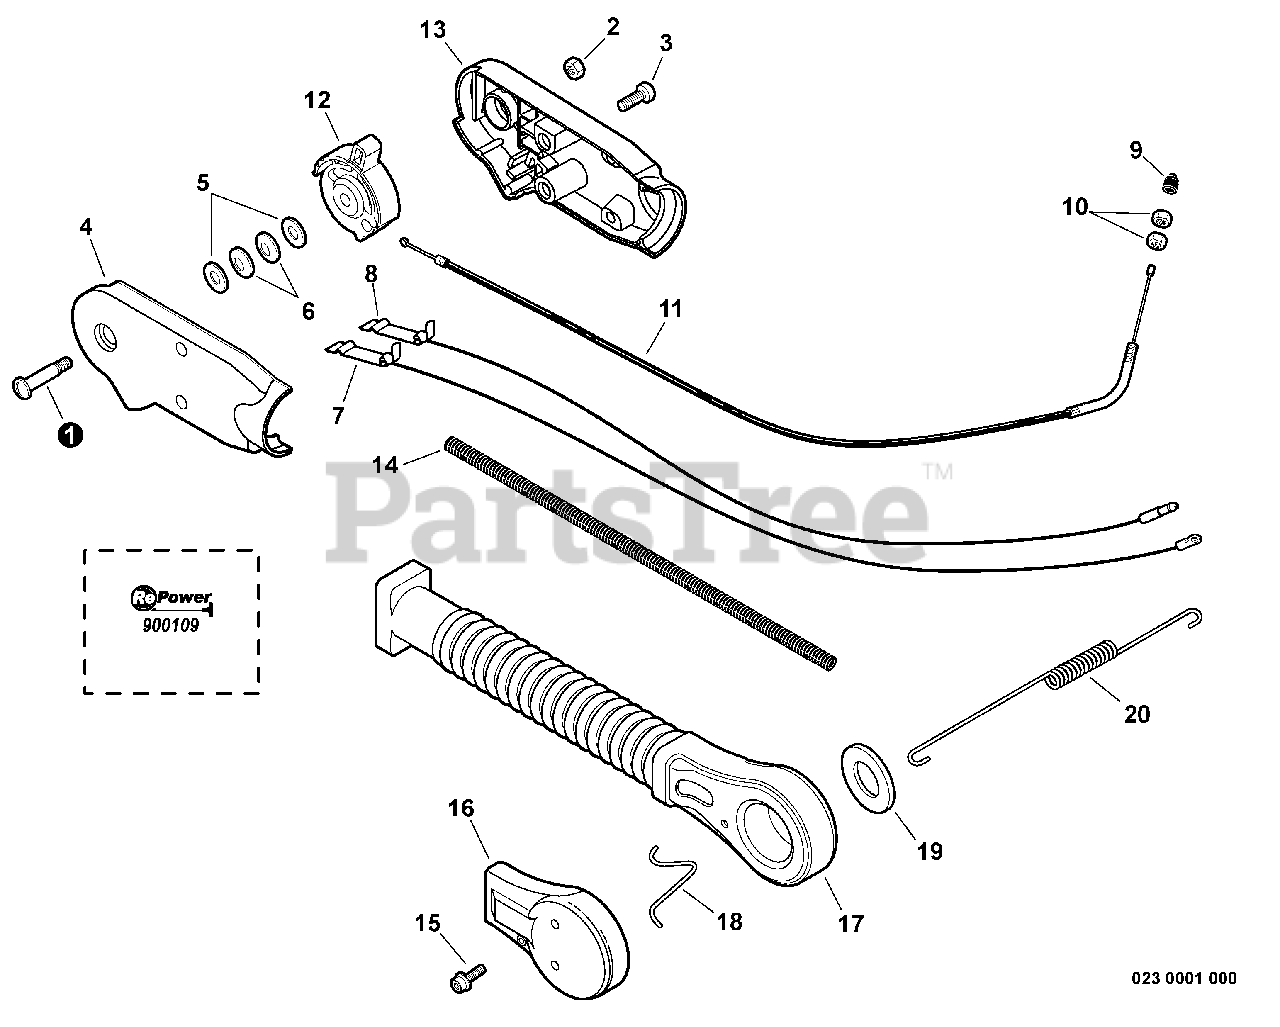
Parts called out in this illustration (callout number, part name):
1	SCREW - 4
2	LOCKNUT - 4
3	SCREW - 5X20
4	HANDLE, CONTROL - LEFT
5	WASHER - 6
6	WASHER - SPRING
8	LEAD - IGNITION
9	CAP, DUST
11	CABLE, THROTTLE
12	LEVER, THROTTLE CONTROL
13	HANDLE, CONTROL - RIGHT
14	TUBE, PROTECTIVE - CORRUGATED
15	SCREW - 5X20
16	FIXTURE, TRIGGER BRACKET - LEFT
17	ARM, TRIGGER
18	HOLDER, SPRING
21	HIP MOUNT THROTTLE CONTROL KIT
